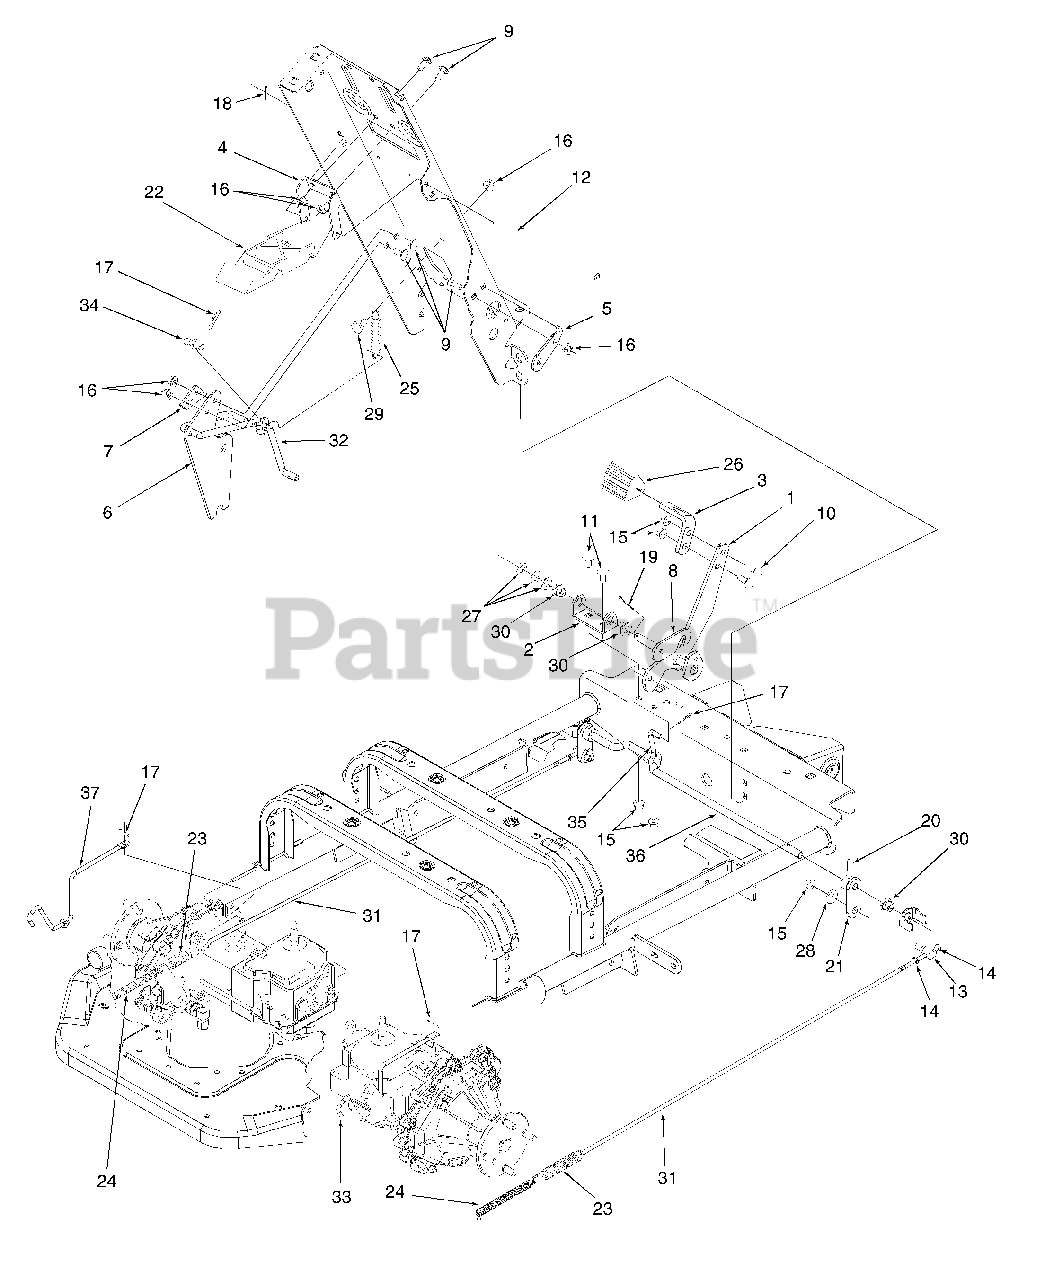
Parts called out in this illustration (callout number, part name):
10	Bolt, Carriage, 3/8-16 x 1.0 GR5
11	Bolt, Carriage, 3/8-16 x .75 GR5
12	Pin, Clevis, 1/4 x 6.65
14	Nut, Hex Jam, 1/4-28
15	Nut, Hex Flange Lock, 3/8-16
16	Nut, Hex Flange Lock, 1/4-20
17	Pin, Internal Cotter
18	Pin, Cotter, 1/16 x .75
19	Pin, Cotter, 3/32 x 1.25
20	Pin, Spiral, 3/16 x 1.0
21	Arm, Brake
22	Lever, Park Brake Engagement
23	Spring, Extension, .75 O.D. x 5.0
24	Spring, Extension
25	Spring, Extension, .5 O.D. x 2.25
26	Foot Pad, Brake
27	Washer, Flat, .536 x .930 x .05
28	Washer, Flat, .385 x 1.0 x .135
29	Bolt, Shoulder, .340 x .285:1/4-20
30	Bearing, Hex Flange, .506 I.D.
31	Rod, Brake
32	Rod, Park Brake Retaining
33	Rod, Hydro Pump Release RH
34	Rod, Park Brake
35	Rod, Park Brake Support
36	Rod, Brake Connecting
37	Rod, Hydro Pump Release LH
